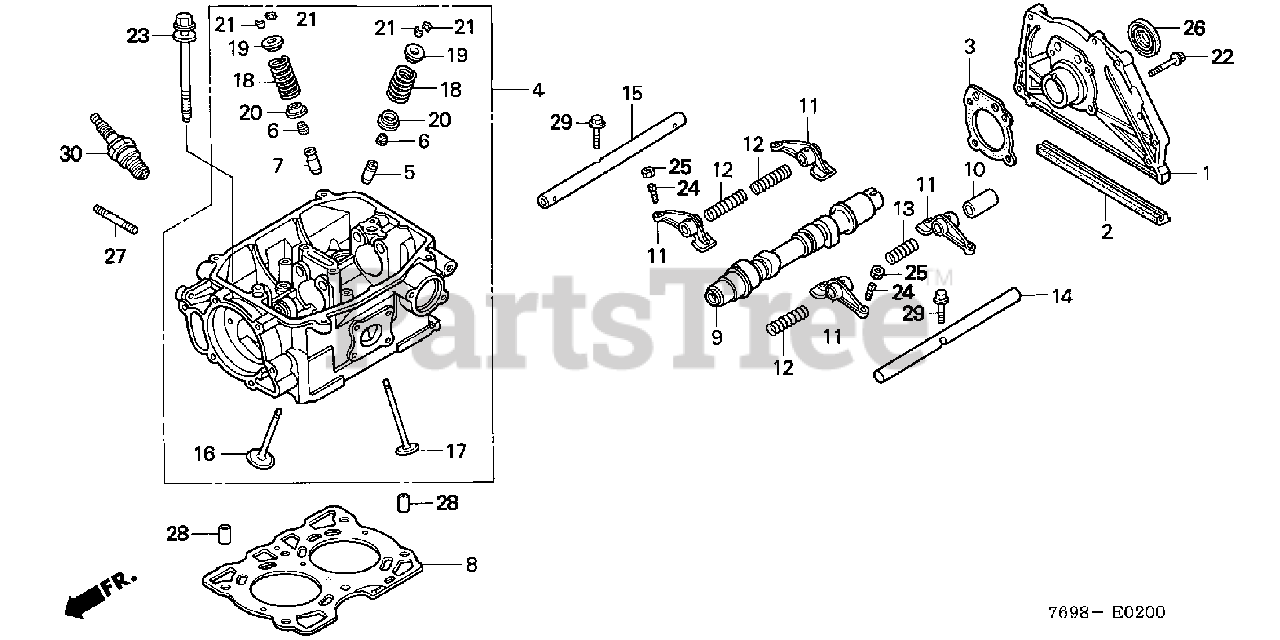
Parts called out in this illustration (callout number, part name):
1	COVER, RR. TIMING BELT
2	GASKET, RR. TIMING BELT COVER
3	GASKET, RR. TIMING BELT COVER
4	CYLINDER HEAD ASSY.
5	GUIDE, VALVE (OS)
6	SEAL, VALVE STEM (ARAI)
7	GUIDE, EX. VALVE
8	GASKET, CYLINDER HEAD
10	COLLAR, ROCKER ARM
11	ARM, ROCKER
12	SPRING, ROCKER ARM A
13	SPRING, ROCKER ARM B
14	SHAFT, IN. ROCKER
15	SHAFT, EX. ROCKER
16	VALVE, IN.
17	VALVE, EX.
18	SPRING, VALVE
19	RETAINER, VALVE SPRING
20	SEAT, VALVE SPRING
21	COTTER, VALVE
22	BOLT, FLANGE (6X30)
23	BOLT-WASHER (10X115)
24	SCREW, TAPPET ADJ.
25	NUT, TAPPET ADJ.
26	OIL SEAL (28X40X8)
27	BOLT 2, STUD (8X22)
28	PIN A, DOWEL (12X20)
29	BOLT, FLANGE (6X30)
30	SPARK PLUG (BPR5ES-11) (NGK)
30	SPARK PLUG (W16EPR-U11) (DENSO)
